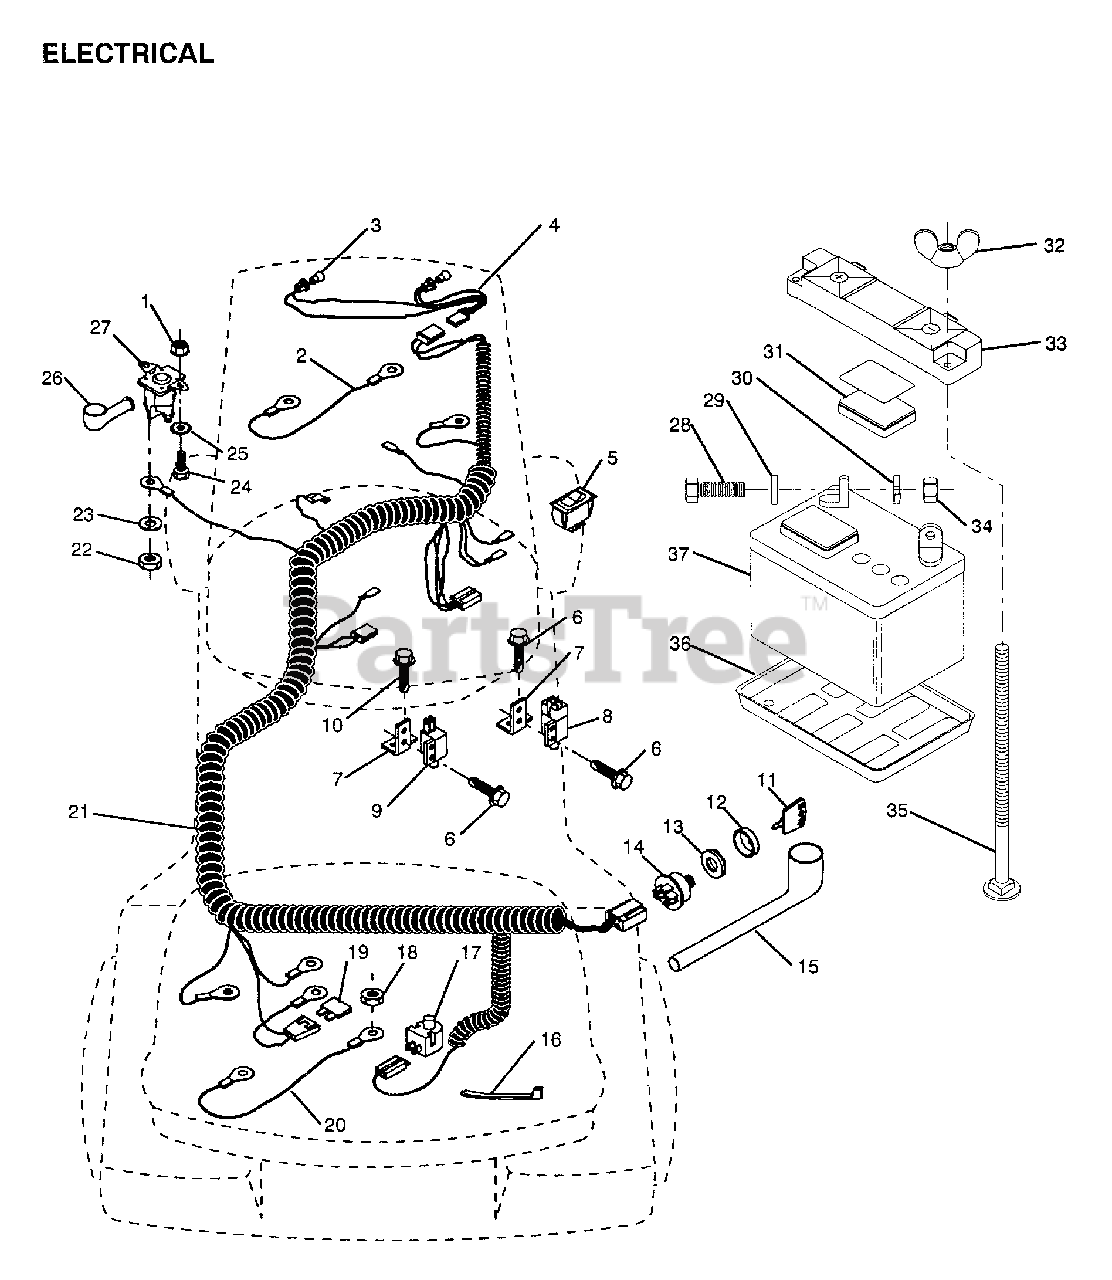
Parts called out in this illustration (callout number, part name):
1	NUT
2	CABLE LTV
5	SWITCH LT
6	SCREW
7	BRACKET LT
8	SWITCH INTERLOCKT
9	SWITCH-INTER. GT
10	SCREW
11	KEY
13	NUT IGNITION
15	COVER IGNITION SW
16	WIRE TIE
17	SWITCH SEAT
19	FUSE HYT
21	"HARNESS,IGNITION"
22	NUT
24	BOLT
28	BOLT LT
29	WASHER
30	LOCKWASHER
31	"CAP,BATTERY "
35	BOLT
36	"TRAY T, BATTERY"
